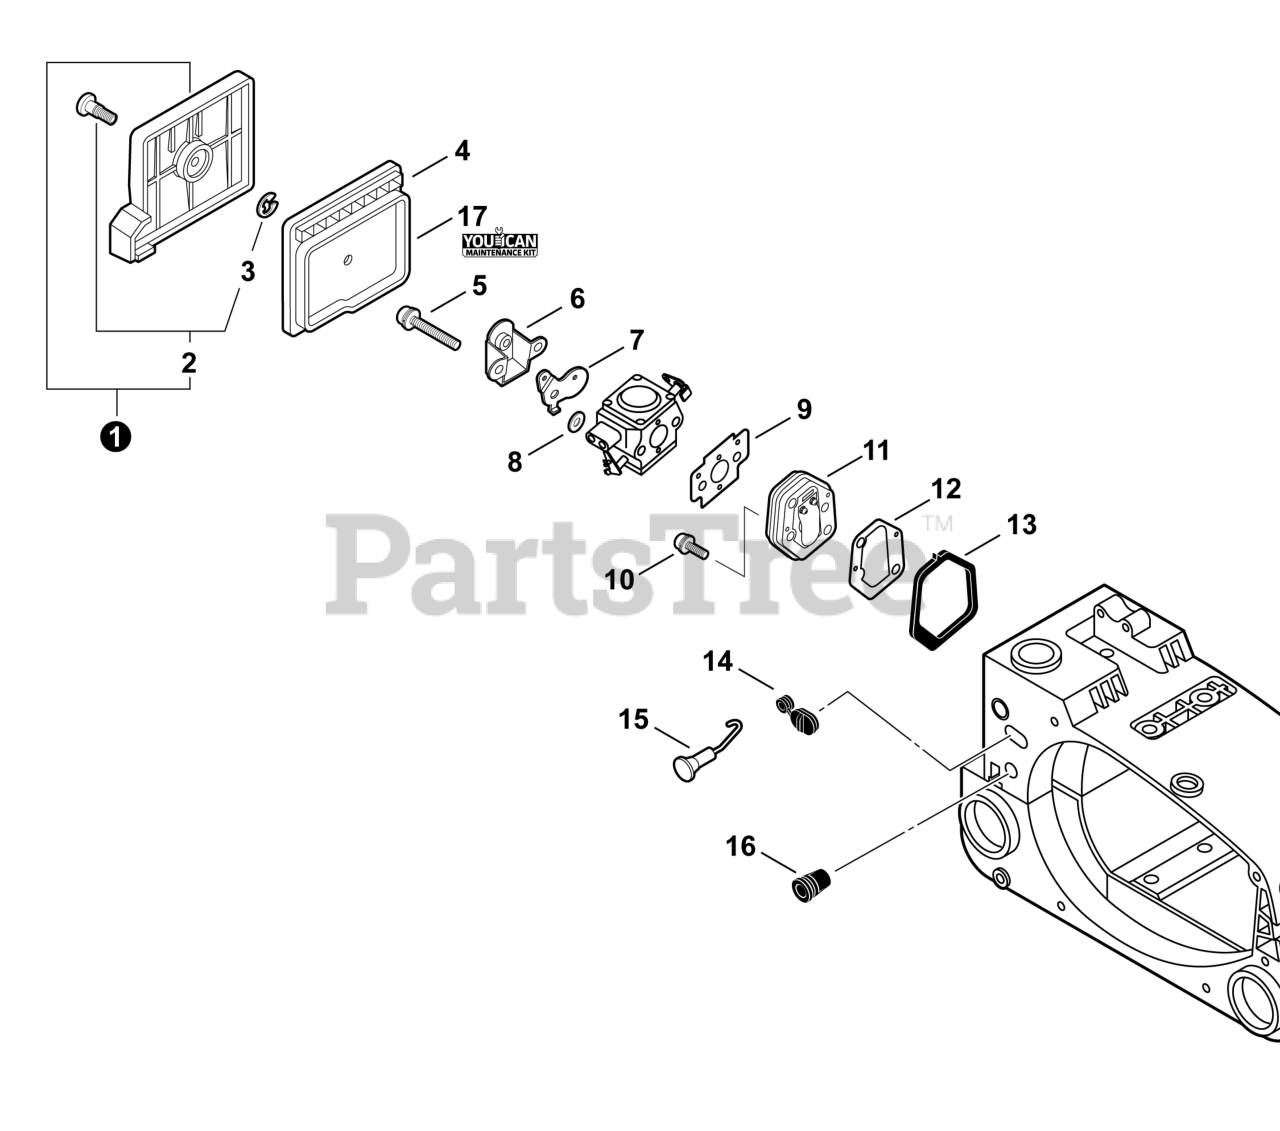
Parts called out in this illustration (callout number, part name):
1	COVER ASSY, AIR FILTER
2	THUMBSCREW
3	E-RING 4
4	FILTER, AIR
5	SCREW 5x45
6	PLATE, PREVENT
7	SHUTTER, CHOKE
8	WASHER 5.2x8x0.8T
9	GASKET, INTAKE
10	SCREW 5x18
11	INSULATOR KIT
12	GASKET, INTAKE
13	SEAL, INTAKE
14	GROMMET, CHOKE
15	ROD, CHOKE
16	GROMMET, IDLE
17	TUNE-UP KIT - YOUCANT
